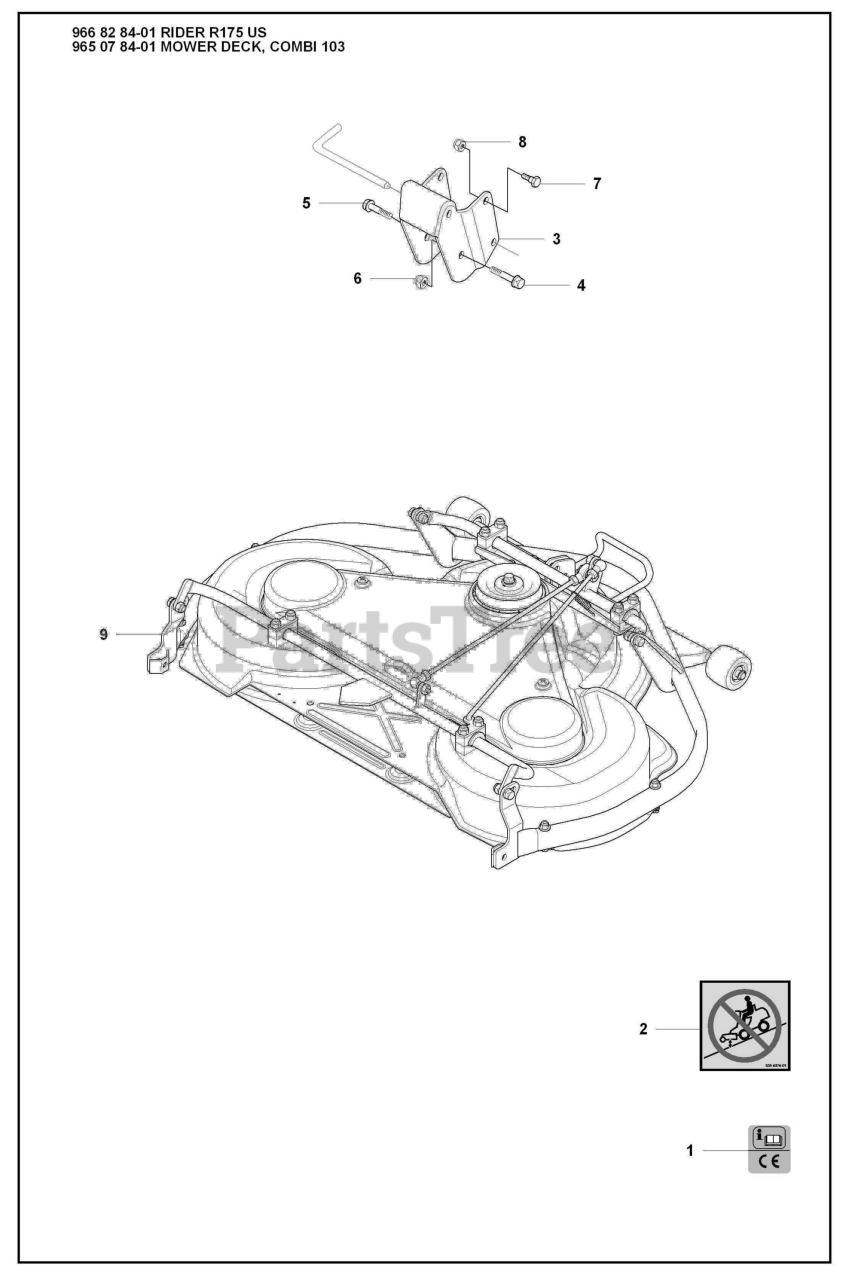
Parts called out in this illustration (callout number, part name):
5	Hex Head Capscrew, M12 X 1.75 X 30 DIN933ZP
6	Lock Nut, Fiber M12 DIN 985 Z/P
8	LOCKNUT M8
9	DECK COMBI 103
